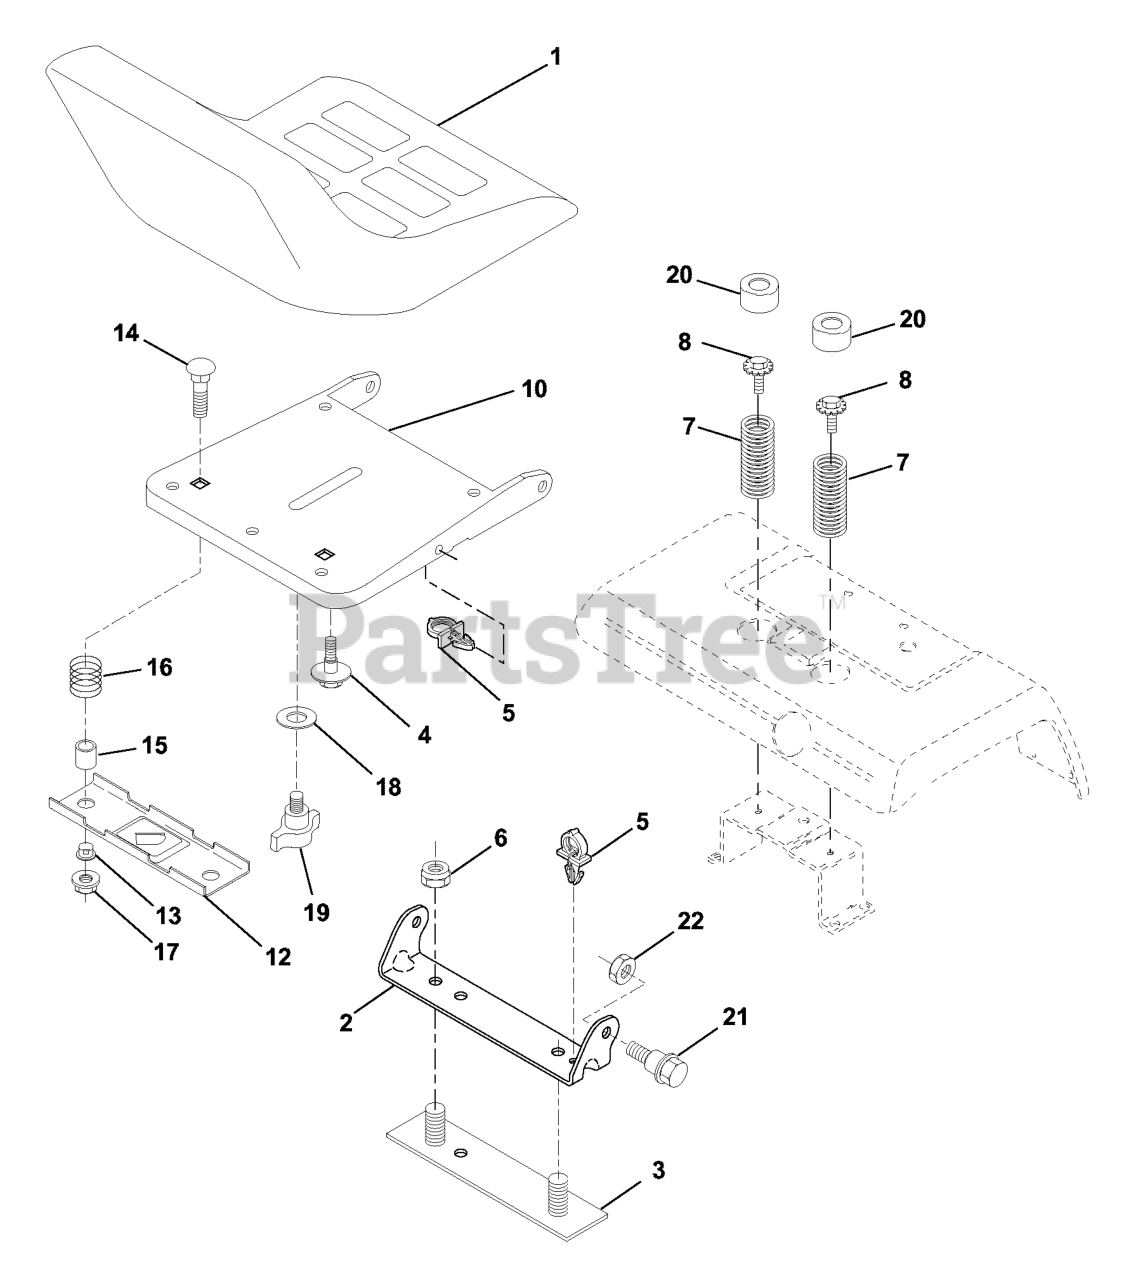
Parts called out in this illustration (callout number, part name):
1	SEAT, GRAY
2	SEAT PIVOT BRKT
3	STRAP
4	BOLT,SHOULD
6	NUT
7	SPRING COMPRESSION
8	BOLT.5/16-18UNCX3/4 W/SEMS.BLK
10	PAN, SEAT
12	BRKT SWITCH
14	BOLT.ROUND.HEAD.SQUARE.NECK
15	SPACER SPLIT
16	SPRING COMPRESSED
17	NUT T
19	KNOB.SEAT.ADJ.WINGNUT
20	CAP SPRING
21	BOLT.SHOULDER.5/16-18
22	NUT.71038.31-18.HEX.NYLOCK
